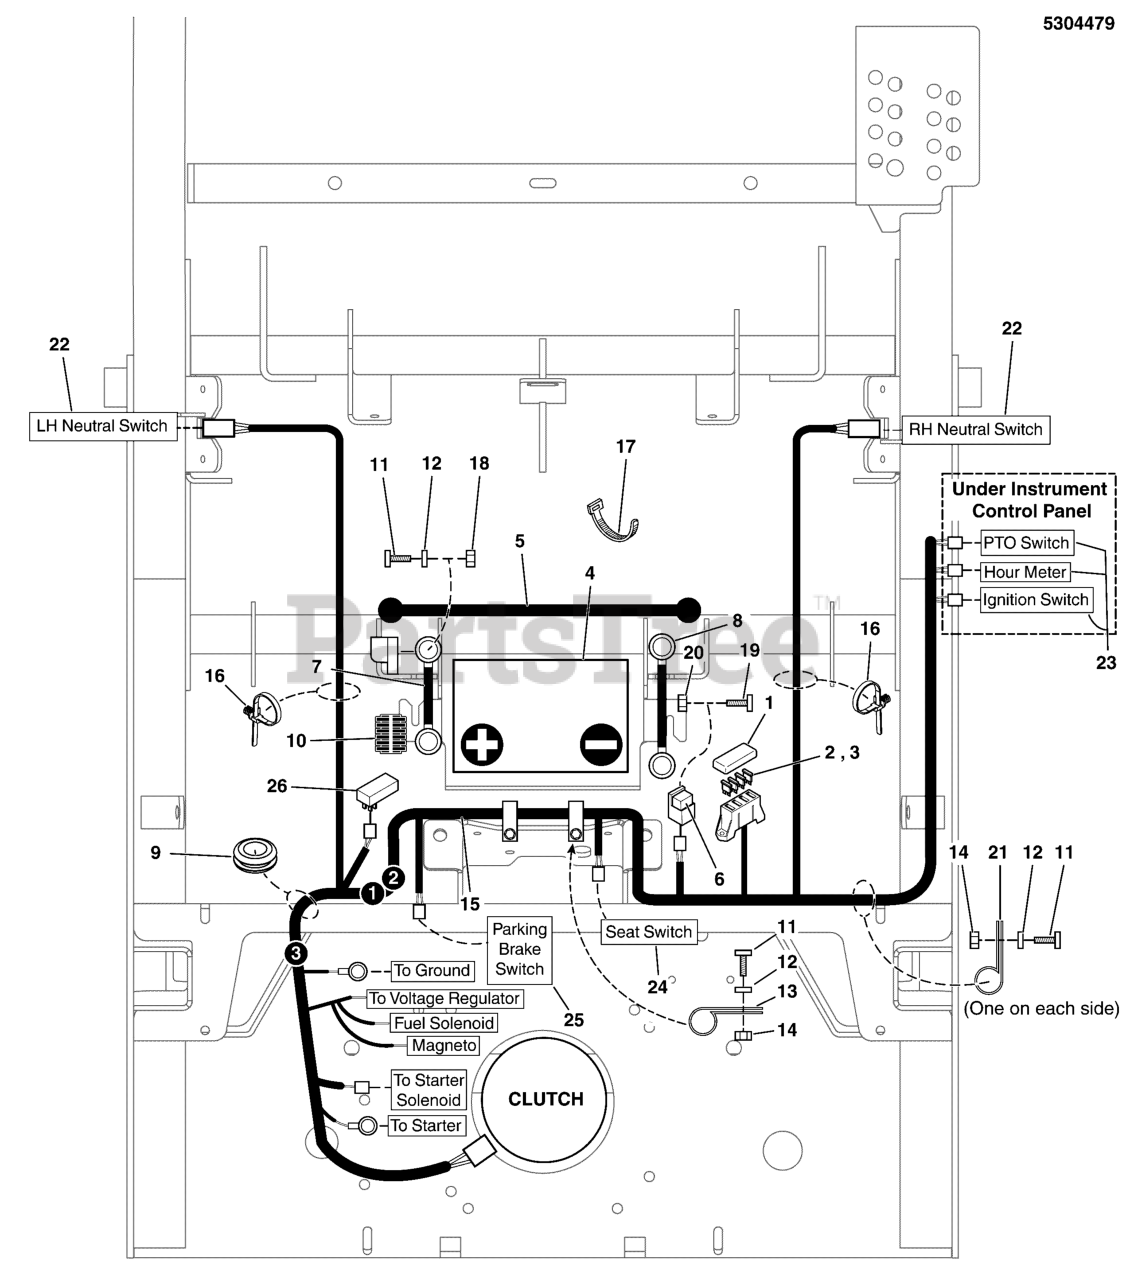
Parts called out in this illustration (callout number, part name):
1	COVER, VINYL FUSEBLOCK
2	FUSE, ATO-15 (15 AMP)
3	FUSE, ATO-20 (20 AMP)
4	BATTERY, 11U1L, 350 CCA
5	STRAP-BLACK RUBB
6	RELAY, 12V, 40A
7	BATTERY CABLE, POS, 22, 1/4-5/16
8	BATTERY CABLE, NEG, 22, 1/4-5/16
9	GROMMET, 2" ID
10	WIRE LOOM, 3/8 ID X 17 IN
11	BOLT, 1/4-20 X 3/4 GD5 CZ
12	WASHER, 1/4 SAE
13	CLAMP, VINYL INSULATED, 1.00
14	NUT, 1/4-20 HEX NYLOCK FLANGE
15	WIRE HARNESS, 35HP KAV, F320Z
16	TIE, SELF-LOCKING, 8", PUSH MOUNT
17	TIE, SELF-LOCKING, 12"
18	NUT, 1/4-20 HEX SERR. FLANGE
19	SCREW, #10-24 X 3/4 ROUND PHILLIPS
20	NUT, #10-24 HEX NYLON LOCK
21	CLAMP, VINYL INSULATED, .625
22	SWITCH, PLUNGER, N.O., BOLT-ON
23	CONTROL SWITCHES (SEE INSTRUMENT CONTROL PANEL GROUP)
24	SWITCH, PLUNGER, N.C.
25	SWITCH, DP NO/NC SNAP-IN
26	MODULE, TIME DELAY
